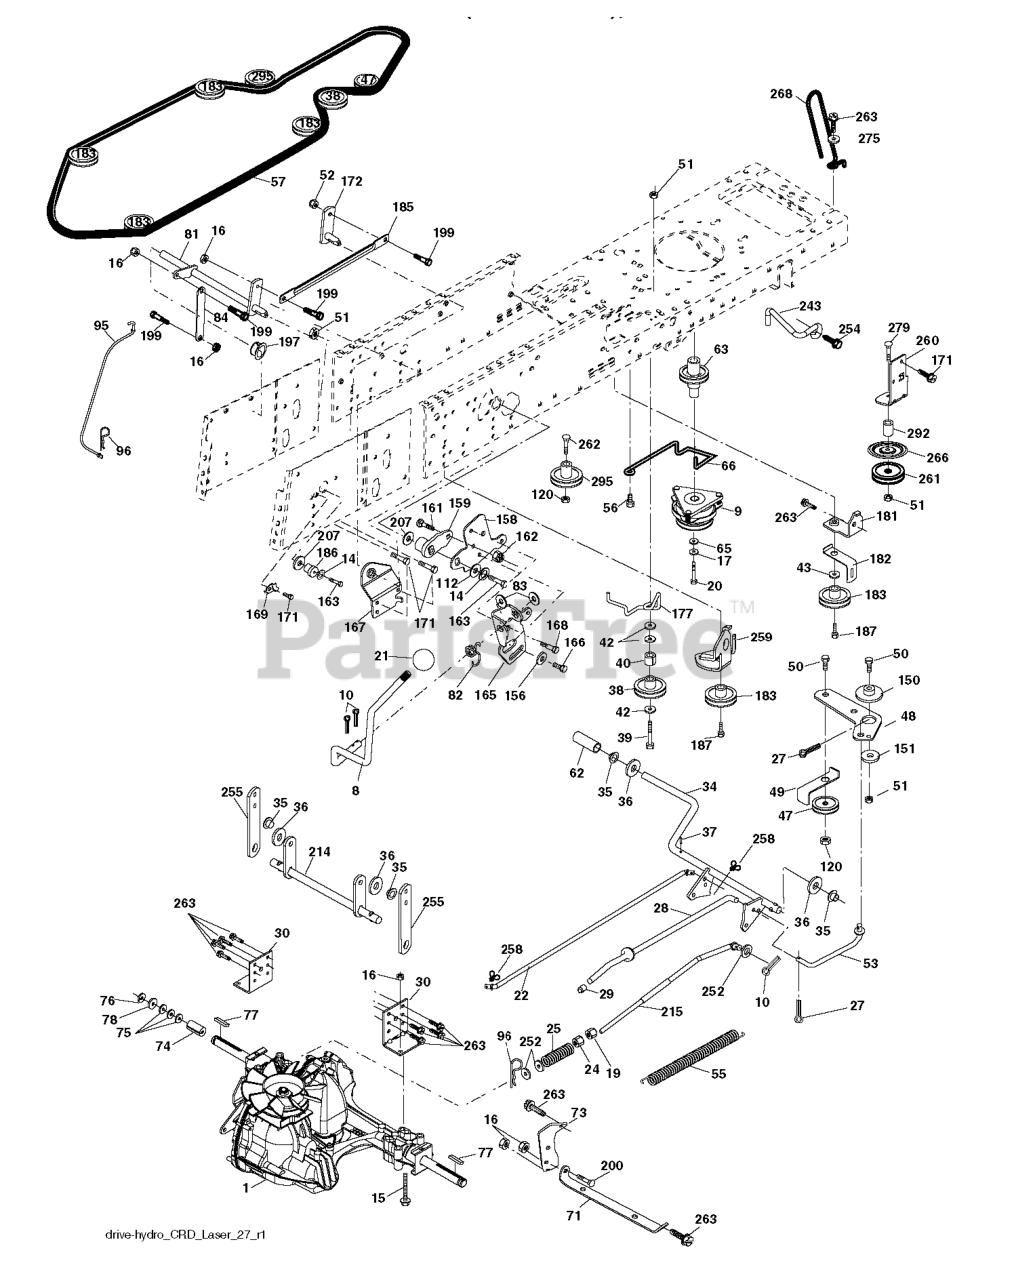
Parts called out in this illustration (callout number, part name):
8	ROD SHIFT FENDER ADJUST LT
9	CLUTCH.ELECTRIC.OGURA.EURO.
10	PIN COTTER
14	LOCKWASHER
15	BOLT HEX 5/16-18 GR 5
16	NUT.71038.31-18.HEX.NYLOCK
19	NUT
20	BOLT HEX 7/16-20X4-1/4"
21	KNOB.DUCKHEAD.1/2
22	ROD
24	NUT
25	SPRING BRAKE ROD
27	COTTER PIN
28	ROD, PARKING BRAKE
29	CAP
30	BRKT, TRNSXLE MNT 20"
34	SHAFT, FOOT PEDAL
35	BEARING.NYLON
37	DRIVE PIN
38	PULLEY.FLAT
42	WASHER
47	IDLER PULLEY
48	BELLCRANK, CLUTCH
49	RETAIN BELT
50	BOLT.3/8-16X1.50
52	LOCKNUT
53	LINK.CLUTCH.7.66.2005
55	SPRING, RETURN LT
56	SCREW.3/8-16
57	V-BELT 113"
62	PEDAL COVER T
63	PULLEY.ENGINE.CVX.LT
65	LOCKWASHER
66	KEEPER BELT ENGINE
71	STRAP TORQUE LH HYDRO
73	STRAP TORQUE RH HYDRO
74	SPACER AXLE
77	SQUARE KEY
81	ASM.CROSS.SHAFT.REAR.CRD.0510
82	SHIFT SPRING
83	WASHER
84	LINK.PNT.TRANSAXLE.0510.CRD
95	LINK
96	RETAINER M
120	NUT LOCK FLG 3/8-16 UNC
150	BUSHING.BELLCRANK.GRD.DR
151	WASHER 12/32X2X10GA
156	WASHER.SRRTD.5/16
158	BRACKET
159	RB HUB.SHIFT
161	BOLT
162	NUT.CROWNLOCK.1/4
165	RP BRACKET
166	CAPSCREW.HXHD.FLG.5/16-18X.625
167	BRACKET.SUPT.SHIFT.CRD
168	BOLT.SHOULDER.5/16-18X
169	PLATE.FASTENING.CROSS.SHAFT
172	LINK
181	BRACKET
182	BELT GUIDE
183	PULLEY.V-IDLER.GRND.DR
185	LINK
186	HUB.TAPERED.ROUND.CRD
187	BOLT.5/16-18X1.25
197	NYLINER SNAP 5/8" ID
199	BOLT SHOULDER 5/16-18 UNC
207	WASHER NYL
214	LEVER
215	ROD
243	BRACKET, ANTI-ROTATION
252	WASHER
254	SCREW 3/8-16X1
255	SHAFT
258	CLIP RETAINER
259	BRACKET
261	FLAT IDLER PULLEY
263	SCREW, 3/8-16X3/4
266	PROTECTOR
268	GUARD MUFFLER
275	WASHER
292	SPACER
295	PULLEY IDLER COMPOSITE
